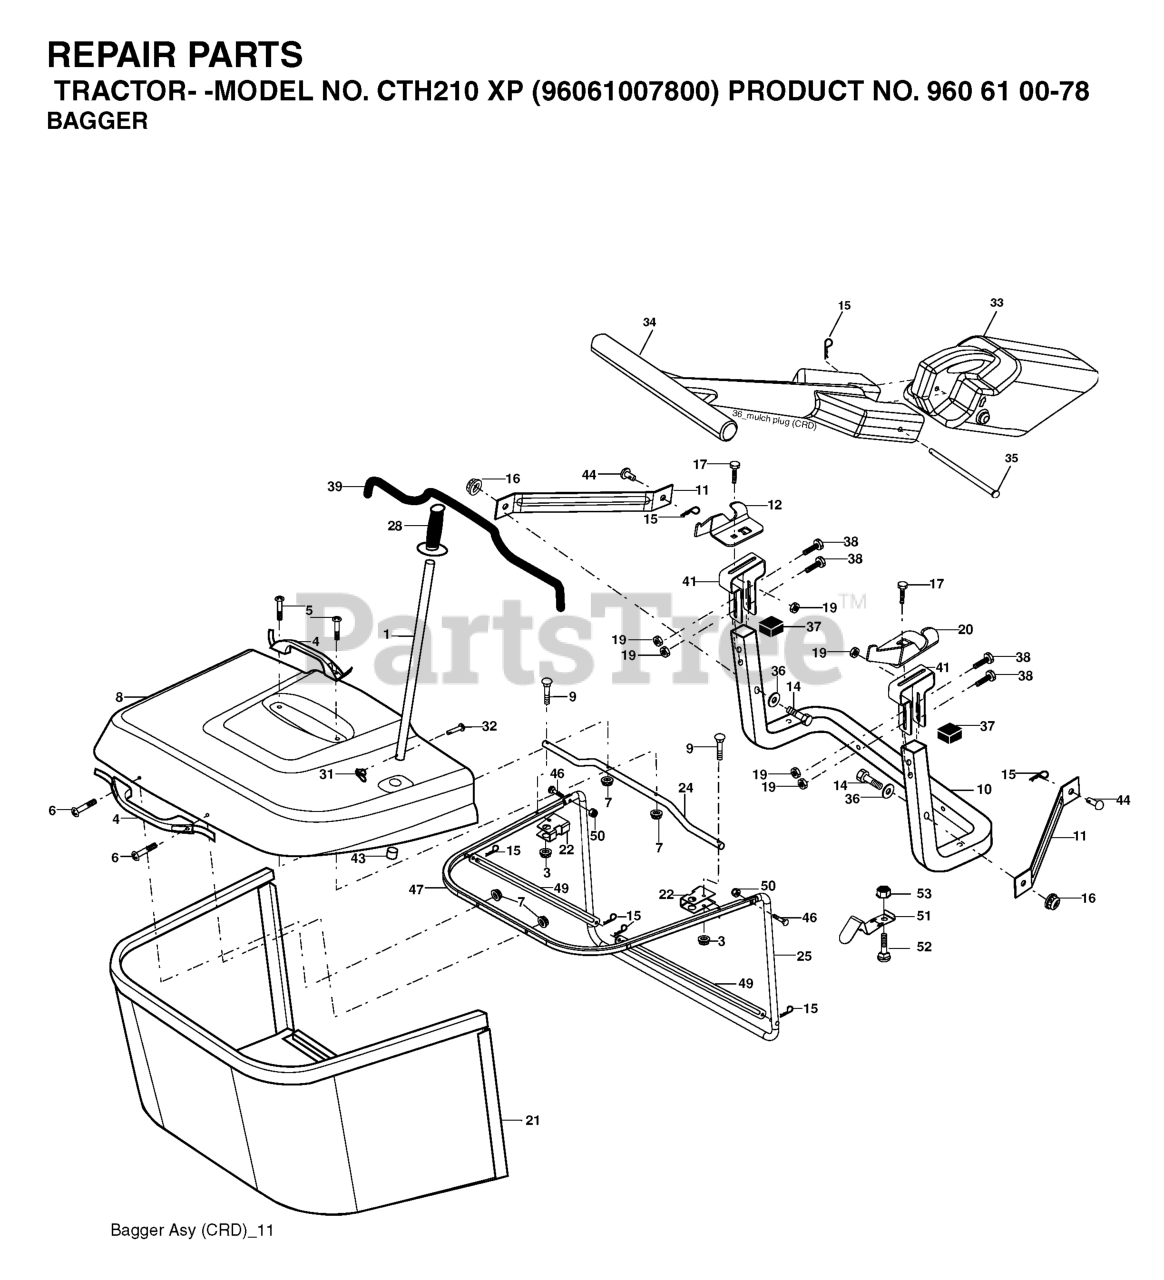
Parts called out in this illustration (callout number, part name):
1	TUBE HANDLE
3	NUT T
4	HANDLE.BAGGER.W/LVRS.BLK.CRD
5	SCREW.PAN.HEAD
6	REPL BY 532 75 00-29
8	COVER.PNT.BGR.CRD.WSLOTS.MS668
9	Bolt Carriage 1/4-20 x 2.25d x Gr.5
10	TUBE
11	BRACKET.SUPPORT.UPPER.BAG.CRD
12	BRKT PIVOT
14	BOLT-HEX EAK
15	RETAINER-SPRNG RB
16	NUT LOCK FLG 3/8-16 UNC
17	RP BOLT 5/16-18 X3/4 ZN/YEL GR
19	NUT LOCK HEX FLANGE 5/16-18
20	BRKT.PIVOT.RH.CRD
22	BRKT.SIDE.BAG.CRD
24	TUBE.PIVOT.BAG.CRD.BLACK
25	PIPE
28	GRIP.HANDLE.BLACK
31	RETAINER CLIP
32	RIVET,DRILLED
33	MULCH PLUG, CTH150
34	HANDLE.MULCHER.92.CRD (2 2)
36	WASHER
37	Plug Support Bagger CRD
38	BOLT.5/16-18X2.5
39	SEAL.TRIM.37'
41	BRKT.VERT.ADJ.BAGGER.CRD
43	PLUG, TUBING END
47	PIPE
49	ROD
51	LATCH
52	BOLT
53	NUT
